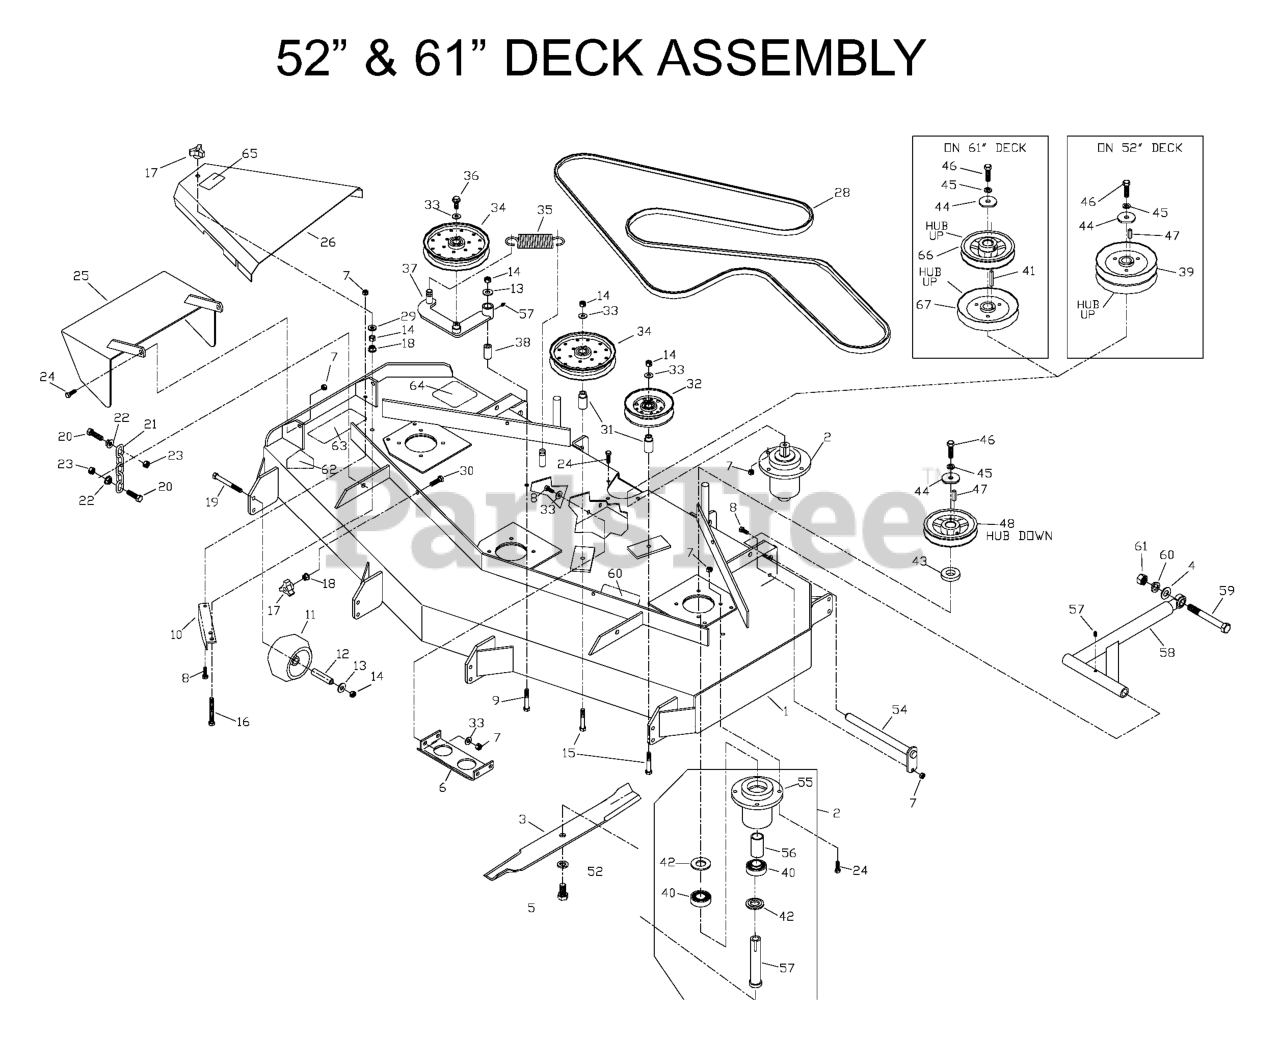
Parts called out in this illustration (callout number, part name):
1	DECK FRONT W/DECALS 61"
2	HOUSING ASSEMBLY
3	BLADE OEM 21" (61" DECK)
4	WASHER 5/8 FLAT
5	HCS 5/8F X 1 1/4
6	DNB GUARD,PAINTED-BLACK
7	NUT 5/16C CENTERLOCK
8	HCS 5/16C X 3/4
9	HCS 3/8C X 3
11	ANTI-SCALP ROLLER
13	WASHER 3/8 FLAT
14	NUT 3/8C CENTERBLOCK
15	SCREW 3/8C X 2 3/4 HEX CAP
16	TAP BOLT 3/8C X 4
17	KNOB, THREE PRONG
18	NUT 3/8C WHIZ
19	HCS 3/8C X 3 1/2
20	HCS 7/16C X 1 1/2
21	LIFT CHAIN
22	NUT 7/16C WHIZ
23	NUT 7/16C CENTERLOCK
24	HCS 5/16C X 1
25	DISCHARGE CHUTE
26	BELT SHIELD (61" DECK)
28	BELT, BLADE (61" DECK)
29	WASHER, 3/8 SEALING
30	HCS 3/8C X 1 1/4 GR5
31	IDLER BUSHING
32	IDLER PULLEY
33	WASHER 5/16 FLAT
34	IDLER PULLEY
36	4CS 3/8C X 1 SERRATED HEAD
38	SLEEVE BUSHING
39	PULLEY, DOUBLE 52"
40	BEARING
41	BUSHING.MACHINE.18.GAUGE
42	MACHINERY BUSHING 10 GA.
44	WASHER, CRANKSHAFT
45	WASHER 7/16 LOCK
46	HCS 7/16F X 1 1/2
47	KEY 1/4 SQ X 1 1/8
48	PULLEY, ENGINE
49	ZERK
50	STRUT, LEFT
51	SCREW 5/8C X 5 HEX CAP
52	LOCKWASHER 5/8
53	NUT 5/8C HEX
57	SPINDLE SHAFT
60	DECAL, BELT ROUTING
62	DECAL, CPSC
63	DECAL, DANGER
64	DECAL, ANTI-SCALP
65	DECAL, NO STEP
67	PULLEY (61" JACK SHAFT)
68	KEY 1/4" SQ X 1 7/8"
539100341	BLADE OEM 18"
539102903	BELT, BLADE 52"DECK
539104578	STRUT, RIGHT
539104588	BELT SHIELD (52" DECK_
539104613	FRONT DECK, 52" W/DECALS
